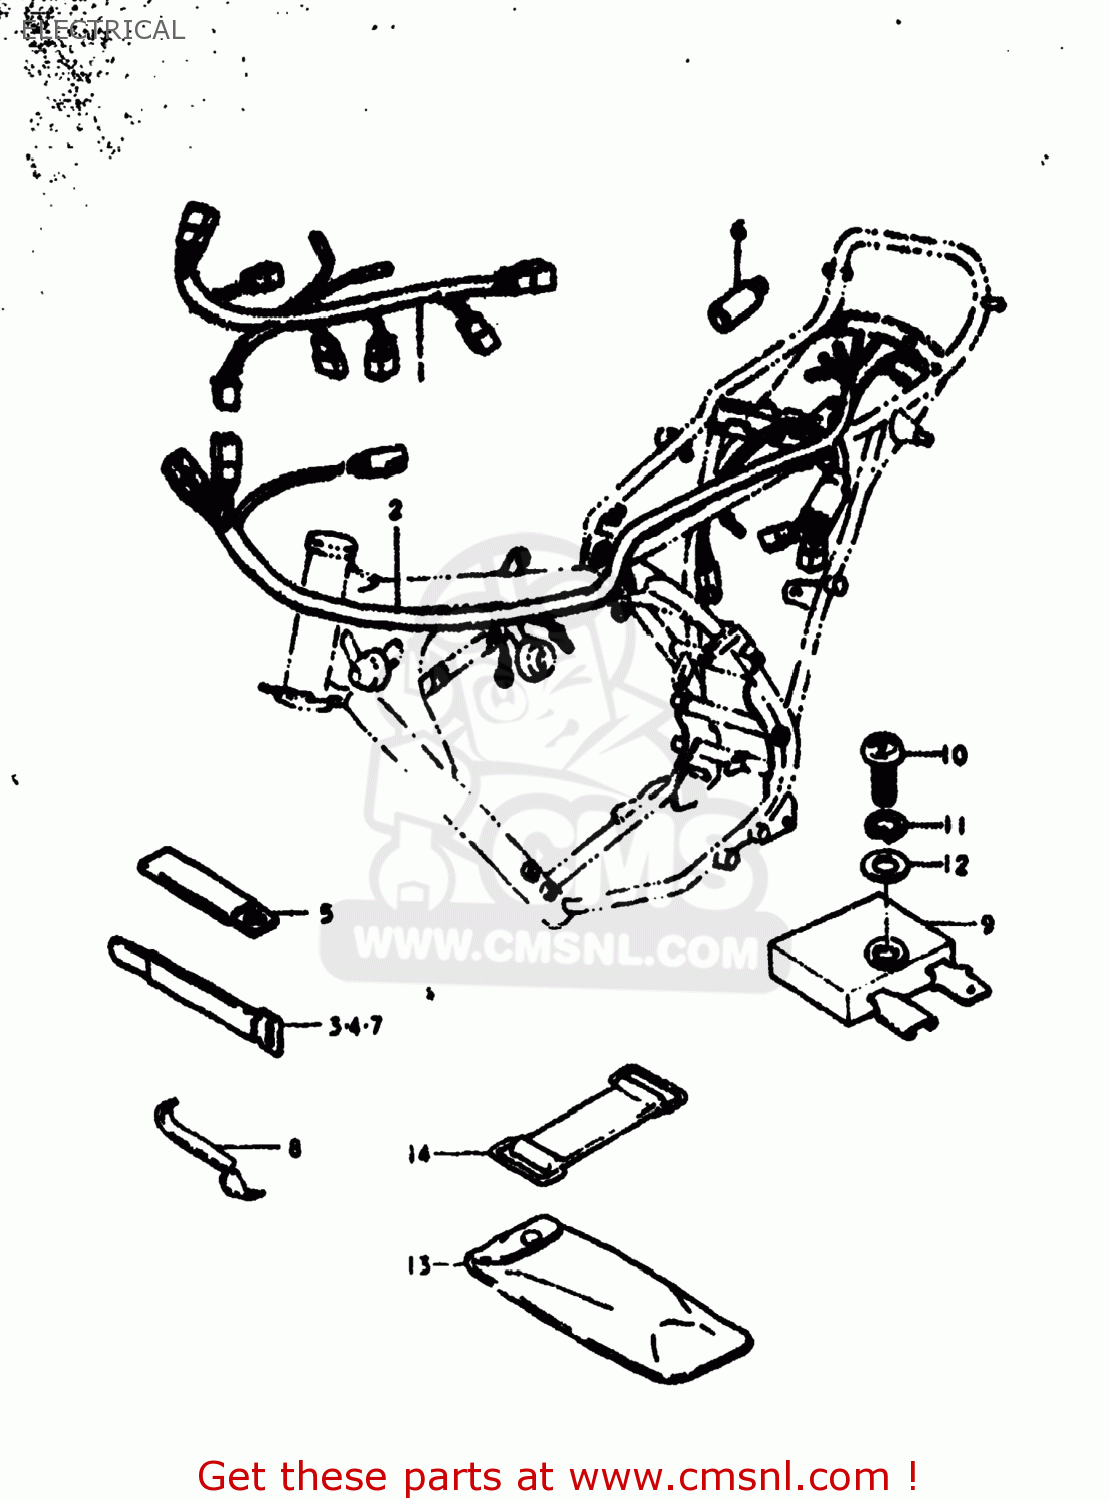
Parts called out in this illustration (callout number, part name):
1	HARNESS,WIRING
2	HARNESS,WIRING NO.2
3	CLAMP
4	CLAMP
5	CLAMP
6	BOOT,WIRING HARNESS
7	CLAMP(L:250)
8	BAND
9	RECTIFIER ASSEMBLY
10	SCREW
11	LOCK WASHER
12	WASHER
13	TOOL SET
14	BAND
